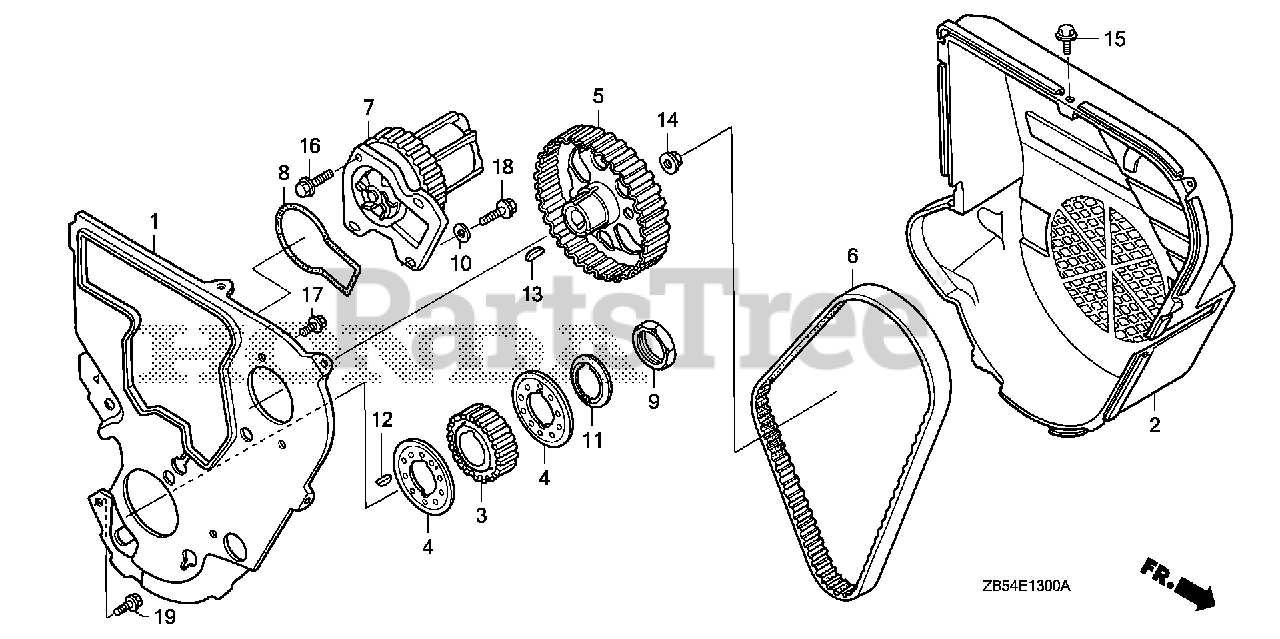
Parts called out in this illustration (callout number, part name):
1	COVER B, TIMING BELT
2	COVER A, TIMING BELT
3	PULLEY, TIMING
4	FLANGE, TIMING PULLEY
5	PULLEY, CAMSHAFT
6	BELT, TIMING
7	WATER PUMP
8	O-RING, WATER PUMP
9	NUT, LOCK (30MM)
10	WASHER, PLAIN (6.5X15)
11	WASHER, LOCK (30MM)
12	KEY, SPECIAL WOODRUFF (25X18)
13	KEY, CAM PULLEY
14	NUT, FLANGE (10MM)
15	BOLT, FLANGE (6X10)
16	BOLT, FLANGE (6X22)
17	BOLT, FLANGE (6X12)
18	BOLT, FLANGE (6X22)
19	BOLT, HEX. (6X10)
19	BOLT, FLANGE (6X10)
